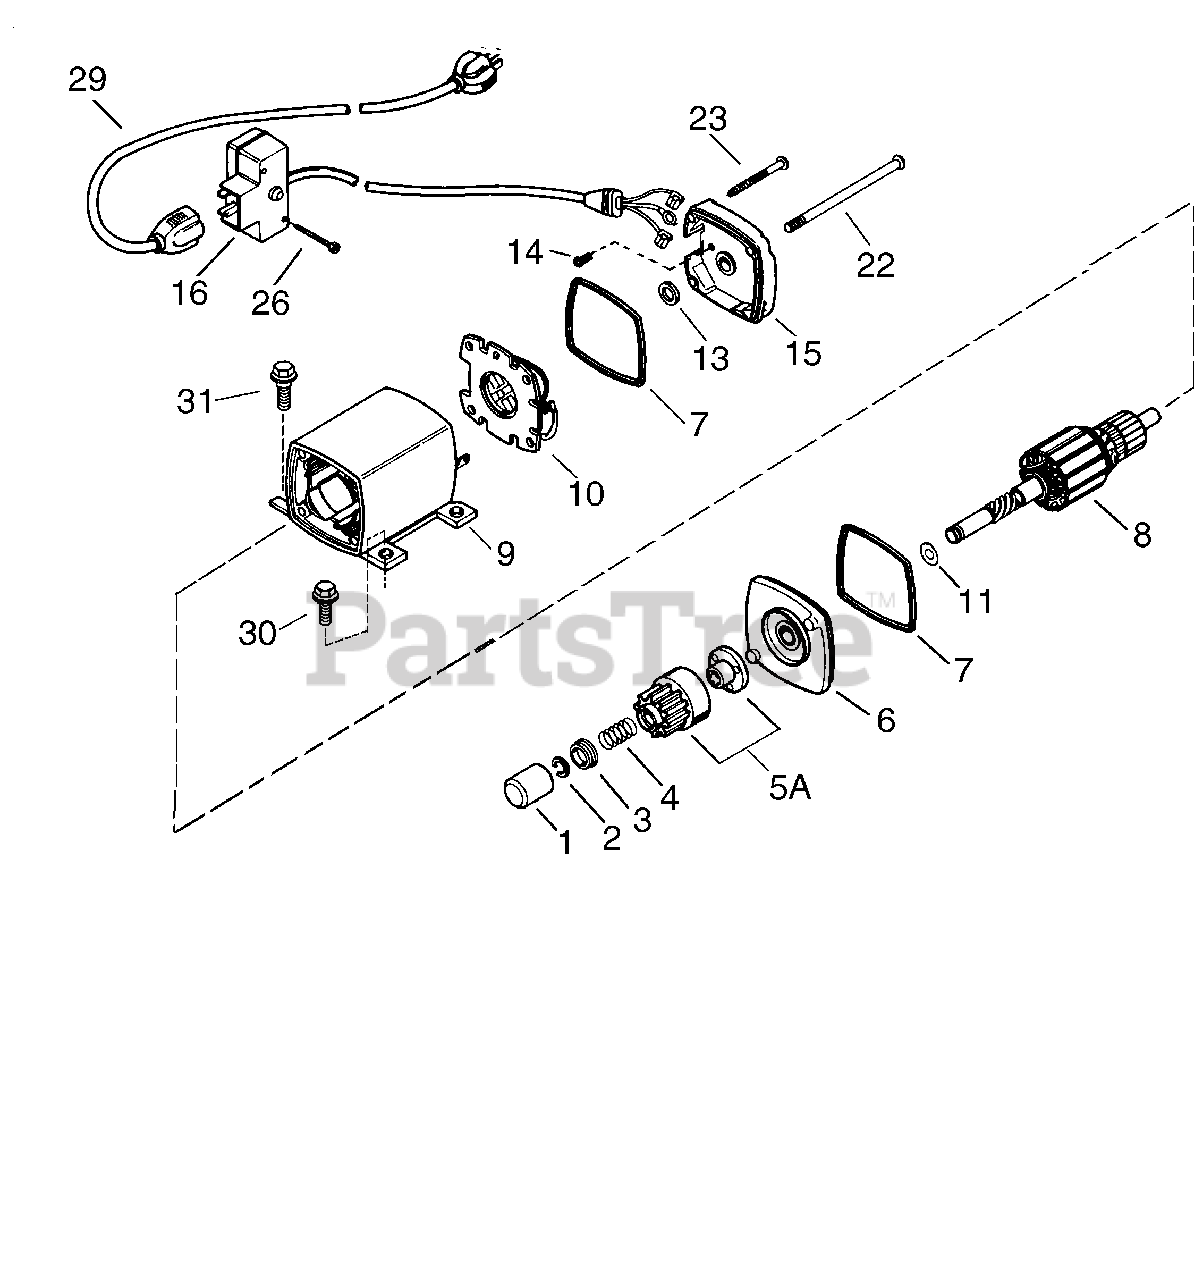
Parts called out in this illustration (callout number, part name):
1	Dust Cover
2	Retainer Ring
3	Spring Retainer
4	Anti-drift Spring
5A	Gear & Nut (Incl. 2)
6	Drive End Cap Ass'y. (Incl. 7)
7	"O" Ring
8	Armature
9	Housing Ass'y.
10	Brush Card Ass'y.
11	Thrust Washer
13	Thrust Washer
14	Ground Screw
15	Commutator End Cap Ass'y. (Incl. 7)
16	Switch Box Ass'y.
22	Case Bolt
23	Ground Screw
26	Screw, 6-32 X 2-1/2"
29	Extension Cord (10'6")
30	Screw, T-30, 1/4-20 x 1/2"
